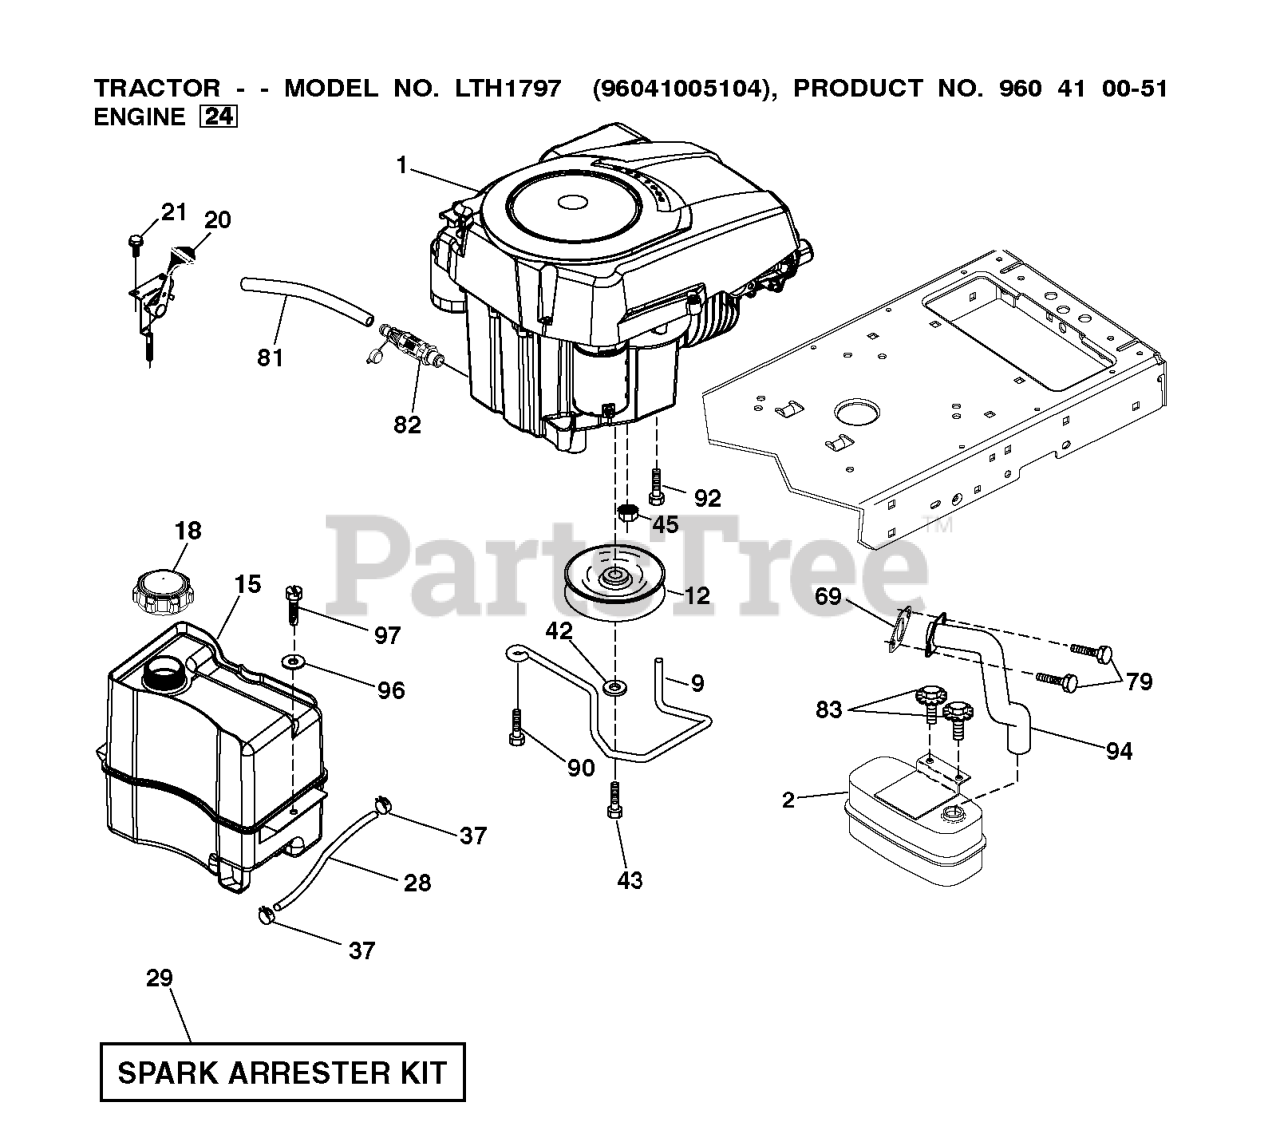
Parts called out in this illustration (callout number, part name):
2	MUFFLER.SINGLE.CYL.KOHL/B&S
9	KEEPER.BELT.ENGINE.4.2
12	PULLY ENGINE
15	RP TANK FUEL FRT 1.5 GAL
18	CAP.FUEL.2.25"VENTED"
20	CONTROL.TH/CK.C.
21	SCREW.#10 X 0.750.BOS
28	LINE.FUEL.20
29	KIT.SPARK ARRESTOR 794945 B&S
37	HOSE CLAMP
42	LOCKWASHER
43	BOLT HEX 7/16-20X4-1/4"
45	NUT
69	GASKET.EXHAUST.KOHLER
79	SCREW.SOCKET HD.5/16-1
81	TUBE, DRAIN OIL ASM.
82	VALUE.OIL.DRAIN
83	BOLT.5/16-18UNCX3/4 W/SEMS.BLK
90	SCREW 3/8-16X1
92	SCREW 3/8-16X1
94	RP.TUBE.EXHAUST.KOHL.COURAGE
97	SCREW HEXWSHR 1/4-20X3/4
